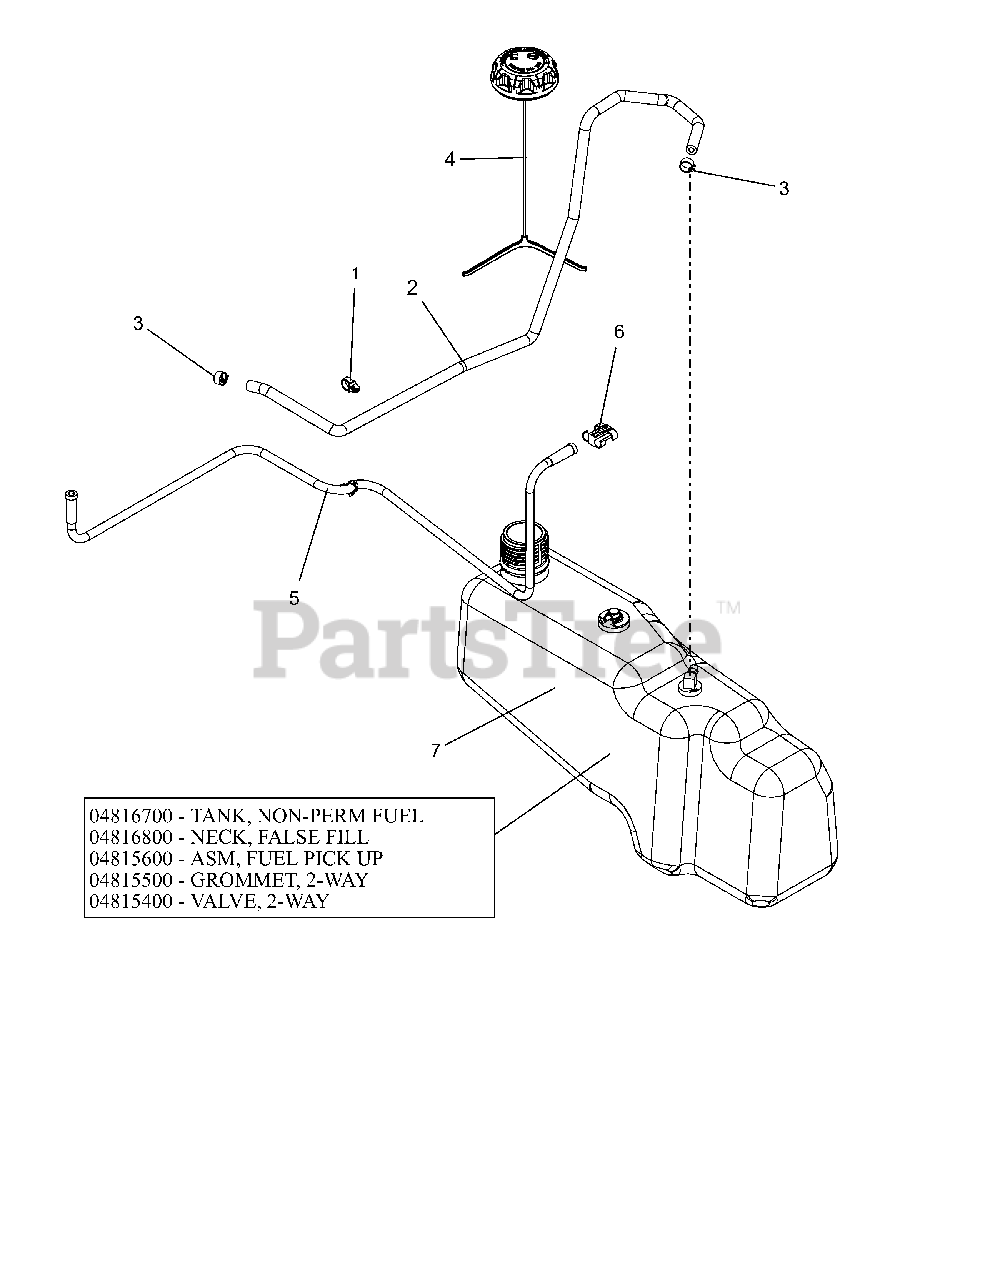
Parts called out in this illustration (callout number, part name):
1	ROUTING CLIP (1/2" ID)
2	HOSE, .25 LOW-PERM BULK GAS
3	CLAMP, FUEL LINE
4	CAP, FUEL VENT-IN 2.25" RATCH.
5	LINE, FUEL VENT KOHLER SMCHOKE
6	CLIP, T, .38-.50
7	ASM,TANK NON-PERM FUEL
7	TANK, ZOOM/ZT NON-PERM, FUEL
7	NECK, FALSE FILL ZOOM/ZT
7	ASM, FUEL PICK-UP ZOOM/ZT 2015
7	GROMMET, 2-WAY
7	VALVE, 2-WAY
